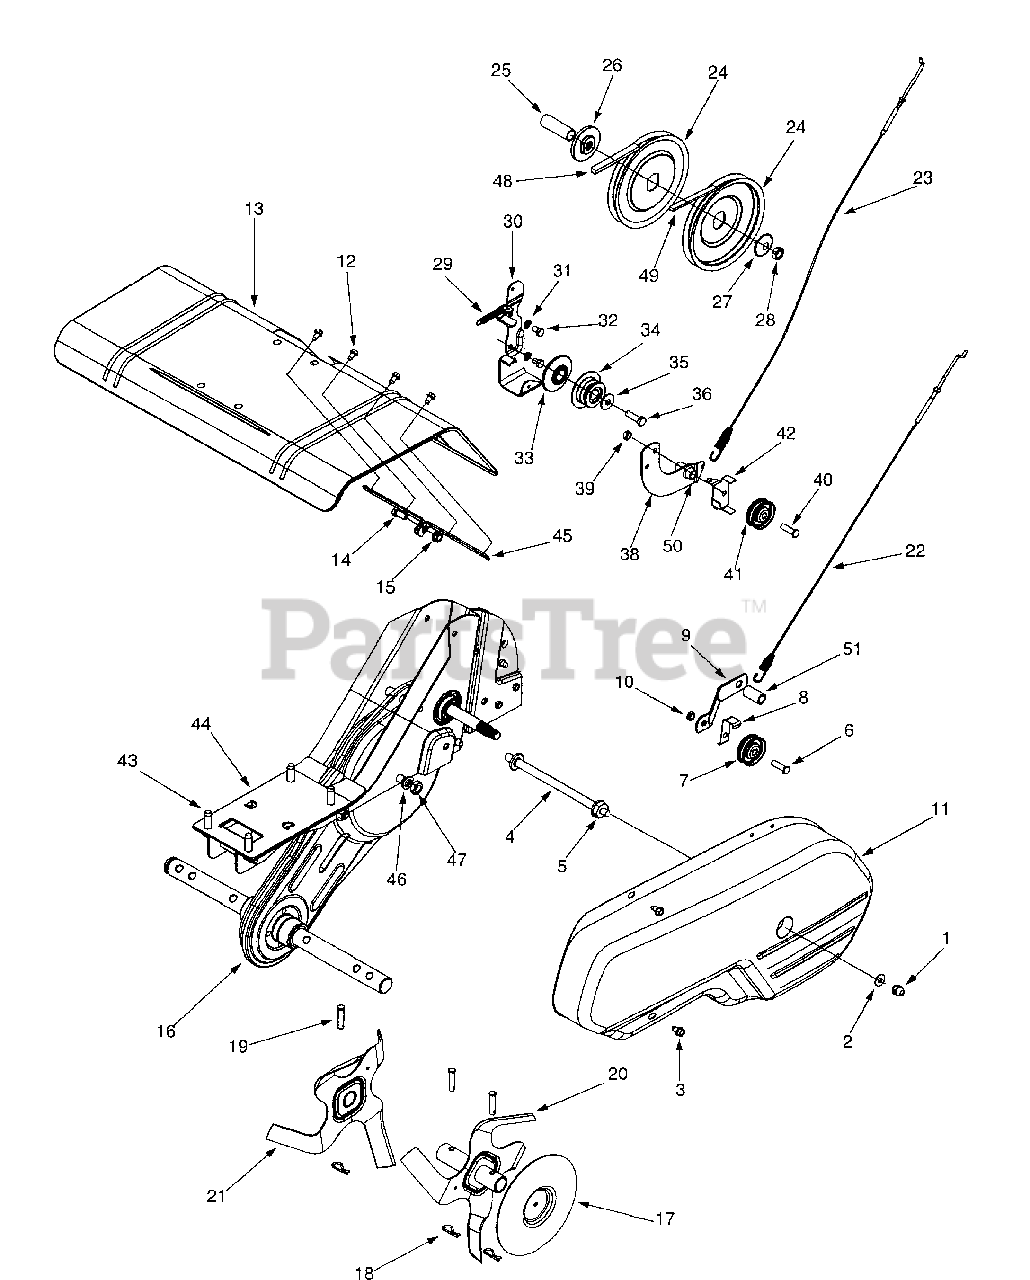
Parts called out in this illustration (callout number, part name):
1	Hex L -Stop nut 1/4-28
2	Flat Wash. .266" I.D. x .625" O.D.
3	Hex Washer TT Tap Scr. 1/4-20 x .5"
4	Belt Cover Bolt
5	Hex Flange Top L-Nut 5/16-18 (Gr.5)
6	Hex Hd. Scr. 3/8-16 x 1.25" Lg. (Gr.5)
7	Fl-Idler 2.12" O.D.
8	Idler Belt Keeper
10	Hex Cent. Jam Nut 3/8-16 Thd.
12	Hex Wash. TT Tap Scr. 1 /4-20 x .5" Lg.
14	Hex Hd. Cap Scr. 5/16-18 x .75" Lg
15	Hex Flange Top L-Nut 5/16-18 (Gr. 5)
16	Chain Case Assembly Complete
18	Internal Cotter Pin
19	Clevis Pin
22	Forward Clutch Cable
23	Reverse Clutch Cable
24	Fl-Pulley 6" Dia.
25	Spacer.64" Dia. x 2.4" Lg.
26	Pulley Mounting Adapter
27	Bell-Wash. .525" I.D. x 1.5" O.D.
28	Hex Jam Nut 1/2-20 Thd. (Gr. 5)
29	Return Spring
30	Reverse Bracket
31	Lock Washer 5/16
32	Hex Bolt 5/16-24 x .5"
33	Inner Engine Pulley Half
34	Outer Engine Pulley Half
35	Bell Washer.396" I.D. x 1/14" O.D.
36	Hex Bolt 3/8-24 x 1.25"
38	Reverse Arm Assembly
39	Hex Cent. Jam Nut 3/8-16 Thd.
40	Hex Cap Bolt 3/8-16 x 1.25" Lg. (Gr. 5)
41	Fl-Idler 2.12" O.D.
43	Hex L-Wash. TT Tap 3/8-16 x 1.25"
46	L-Wash. 7/16" I.D.
47	Hex Nut 7/16-20 Thd.
48	V-Belt (Forward)
49	V-Belt (Reverse)
50	Shld. Bolt
51	Shld. Bolt
